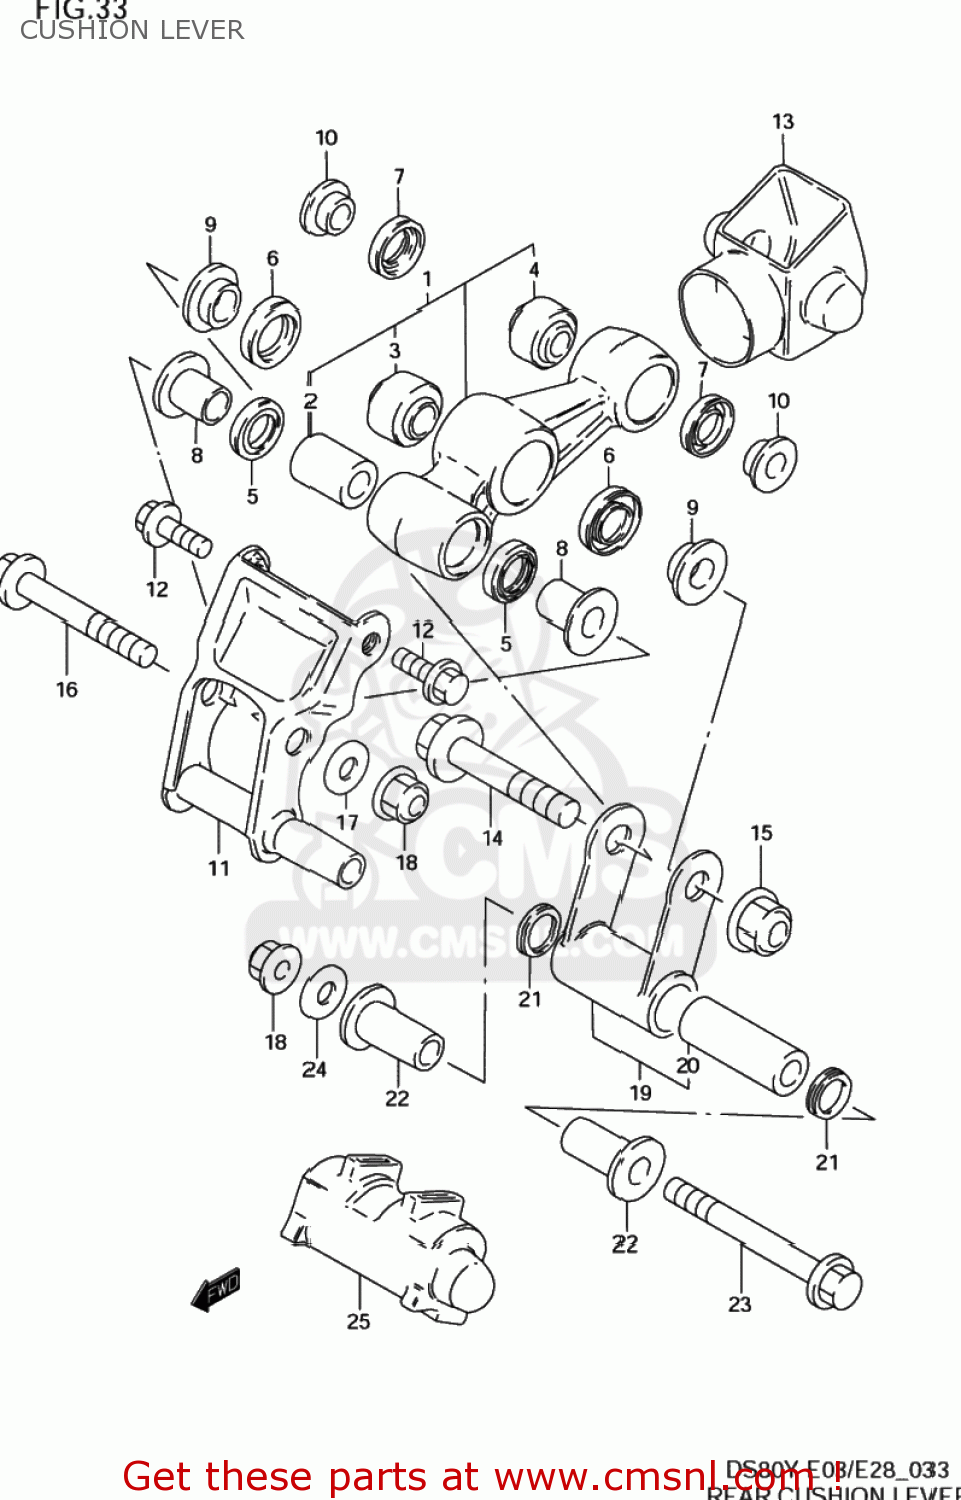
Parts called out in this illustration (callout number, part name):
1	LEVER SET,RR CUSHION
2	BUSHING,CUSHION FR(15X20X31)
3	BEARING(12X26X16)
4	BEARING(10X24X15)
5	DUST SEAL,RR CUSHION LEVER FR
6	DUST SEAL,RR CUSHION LEVER CTR
7	DUST SEAL,RR CUSHION LEVER RR
8	SPACER,RR CUSHION LEVER FR
9	SPACER
10	SPACER
11	HOLDER,RR CUSHION LEVER
12	BOLT,RR CUSHION LEVER HOLDER
13	BOOT,RR
14	BOLT(12X55)
15	NUT 12MM
16	BOLT(10X65)
17	WASHER(10.5X22X1.6)
18	NUT
19	LOD SET,RR CUSHION
20	BUSHING,LOD LWR(15X20X54)
21	DUST SEAL,LEVER CUSHION UNIT
22	SPACER,RR CUSHION ROD LWR
23	BOLT,RR CUSHION ROD LWR
24	WASHER(10.5X22X1.6)
25	BOOT,LWR
